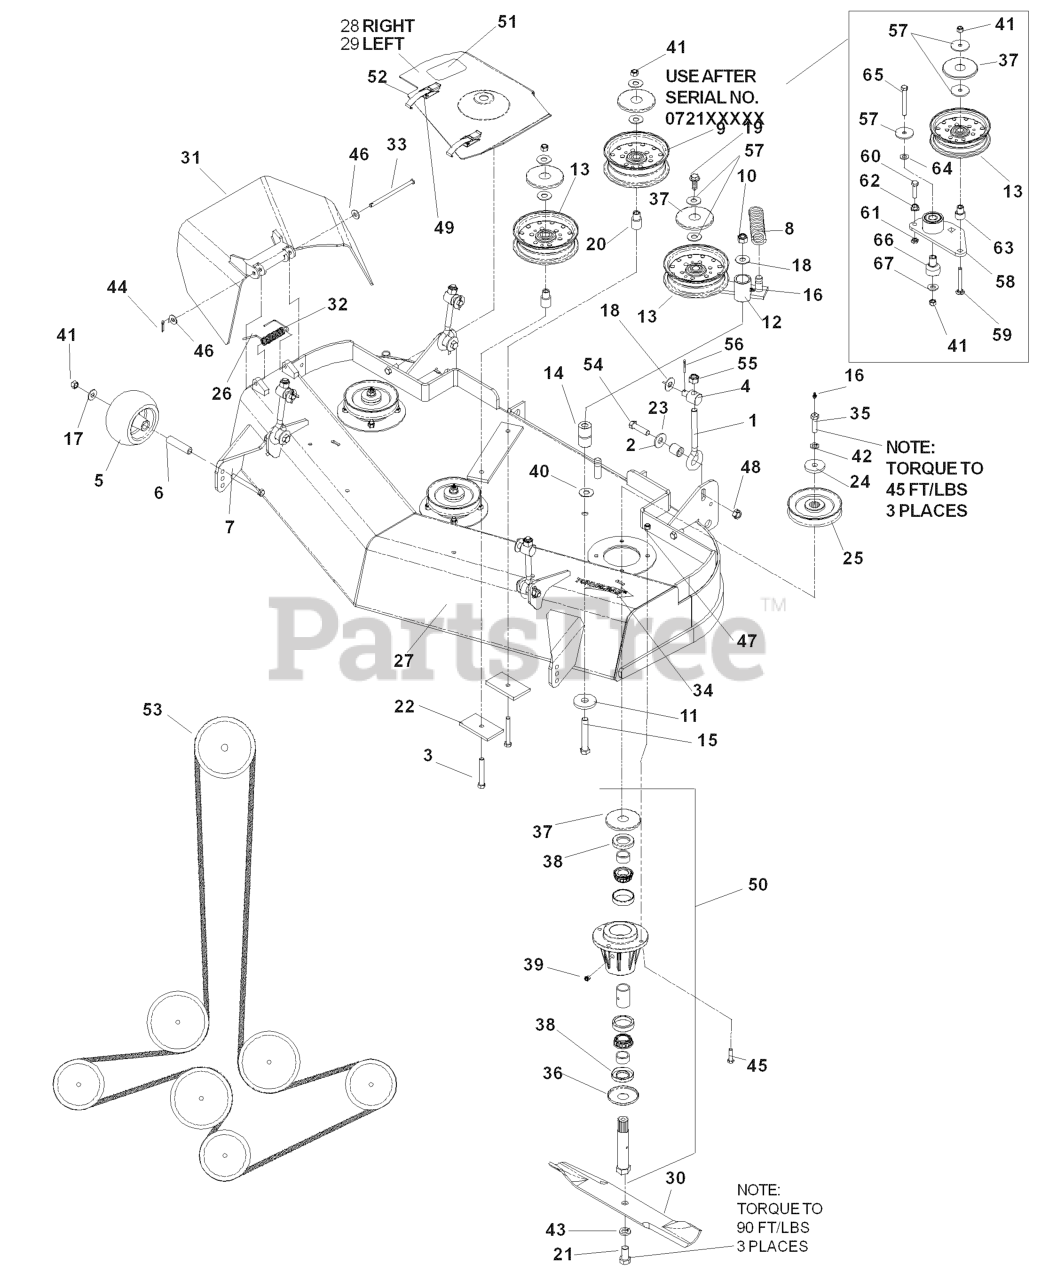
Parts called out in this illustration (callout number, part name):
3	SCREW 3/8C X 2 3/4 HEX CAP
5	ANTI-SCALP ROLLER
7	HCS 3/8C X 3 1/2
9	IDLER PULLEY (TALL)
10	NUT 1/2-13 HEX NYLOC ZD
11	WASHER, SUPPORT
13	IDLER PULLEY
14	PIVOT BUSHING
15	HCS 1/2C X 3 1/4
16	ZERK
17	WASHER 3/8 FLAT
18	WASHER 1/2 FLAT
19	4CS 3/8C X 1 SERRATED HEAD
20	IDLER BUSHING
21	HCS 5/8F X 1 1/4
22	SUPPORT PLATE
23	SPRING WASHER - .50
24	SPINDLE WASHER
25	RP PULLEY - 42/48"
26	CAP-SLEEVE
27	DECK W/DECALS 42"
28	BELT SHIELD ASM RH
29	BELT SHIELD ASM LH
30	BLADE 14-5/8" TUNNEL RAM
31	DISCHARGE CHUTE 42"
32	SPRING - TORSION
33	PIN-CLEVIS 5/16 DIA X 5.19 ZD
34	DECAL, TUNNEL RAM 4"
35	HCS 7/16-20 GD 8 SPEC
36	BOTTOM DUST CAP
37	TOP DUST CAP
38	SHAFT SEAL
39	PLUG-VENTED
40	WASHER 1/2 X 1.44 HRD ZD
41	NUT 3/8-16 NYLOC
42	WASHER 7/16 LOCK
43	LOCKWASHER 5/8
44	RP_COTTER PIN 1/8 X 3/4
45	HCS 5/16C X 1 1/4
46	WASHER 5/16 FLAT
47	NUT 5/16 NYLOC
48	NUT 7/16C CENTERLOCK
49	RIVET, BLIND, 5/32 DIA
50	HSG KIT 52/61 RIBBED
51	DECAL, EURO SEVERING
52	DRAW LATCH
53	DECK BELT
54	HCS 7/16 - 14 X 1 3/4
55	NUT 1/2-13 HEX NYLOC ZD
56	PIN COTTER 1/8 X 1 ZD
57	WASHER, 3/8 SPEC
58	ARM-IDLER W/BRG
59	RHSNB 3/8-16 X 2.75
60	HCS 3/8-16 X 1-1/2
61	NUT 3/8-16 HEX JAM
62	NUT 3/8C WHIZ
63	BUSHING, IDLER
64	WASHER 3/8 SAE FLAT
65	HCS 3/8C X 3
66	PIVOT, BEARING
67	WASHER 3/8 FLAT
